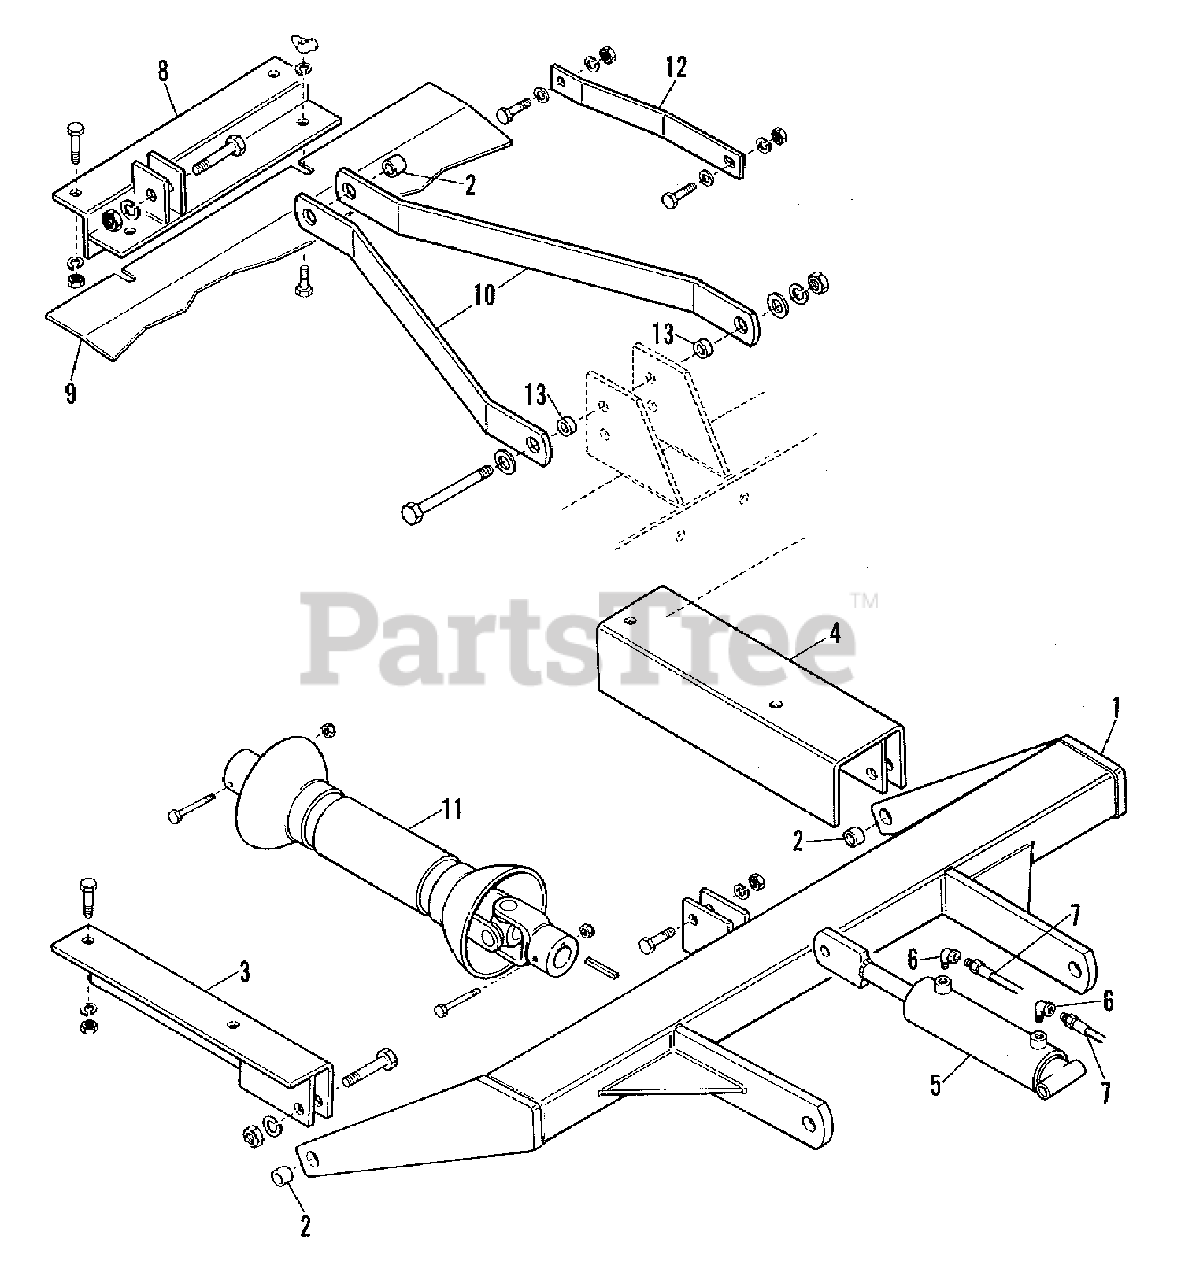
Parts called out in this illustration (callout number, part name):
1	CAPSCREW, 1/NC x 2
1	LOCKWASHER, 1/2
3	BRACKET, Mounting, LH.
3	CAPSCREW, 1/2NC x 1-1/4
3	BOLT, Carriage, 1/2NC x 2
3	LOCKWASHER, 1/2
4	BRACKET, Mounting, R.H.
4	CAPSCREW, 1/2NC x 1-1/4
4	BOLT, Carriage, 1/2NC x 2
4	LOCKWASHER, 1/2
5	CYLINDER, Hydraulic, Complete
5	BOLT, Carriage, 1/2NC x 2
5	CAPSCREW, 1/2NC x 1-1/4
5	WASHER, Plain
5	LOCKWASHER, 1/2
6	ELBOW, 90 Degrees, 1/4NC
7	HOSE ASSEMBLY, Hydraulic (102" Long)
8	BRACKET, Hitch, Upper
8	BOLT, Round Head Square nk., 3/8NC x 1
8	LOCKWASHER, 3/8
9	BOLT, Round Head Square nk., 3/8NC x 1
9	WASHER, Plain, 7/16 x 1 x 14 Ga.
9	LOCKWASHER, 3/8
9	NUT, Wing, 3/8NC
11	PTO ASSEMBLY
11	BOLT, Carriage, 1/4NC x 2-1/2, Gr. 8
11	NUT, Cone Lock, 1/4NC
12	STRAP, Support
12	BOLT, Round Head Square nk., 3/8NC x 1
12	WASHER, Plain, 7/16 x 1 x 14 Ga.
12	LOCKWASHER, 3/8
